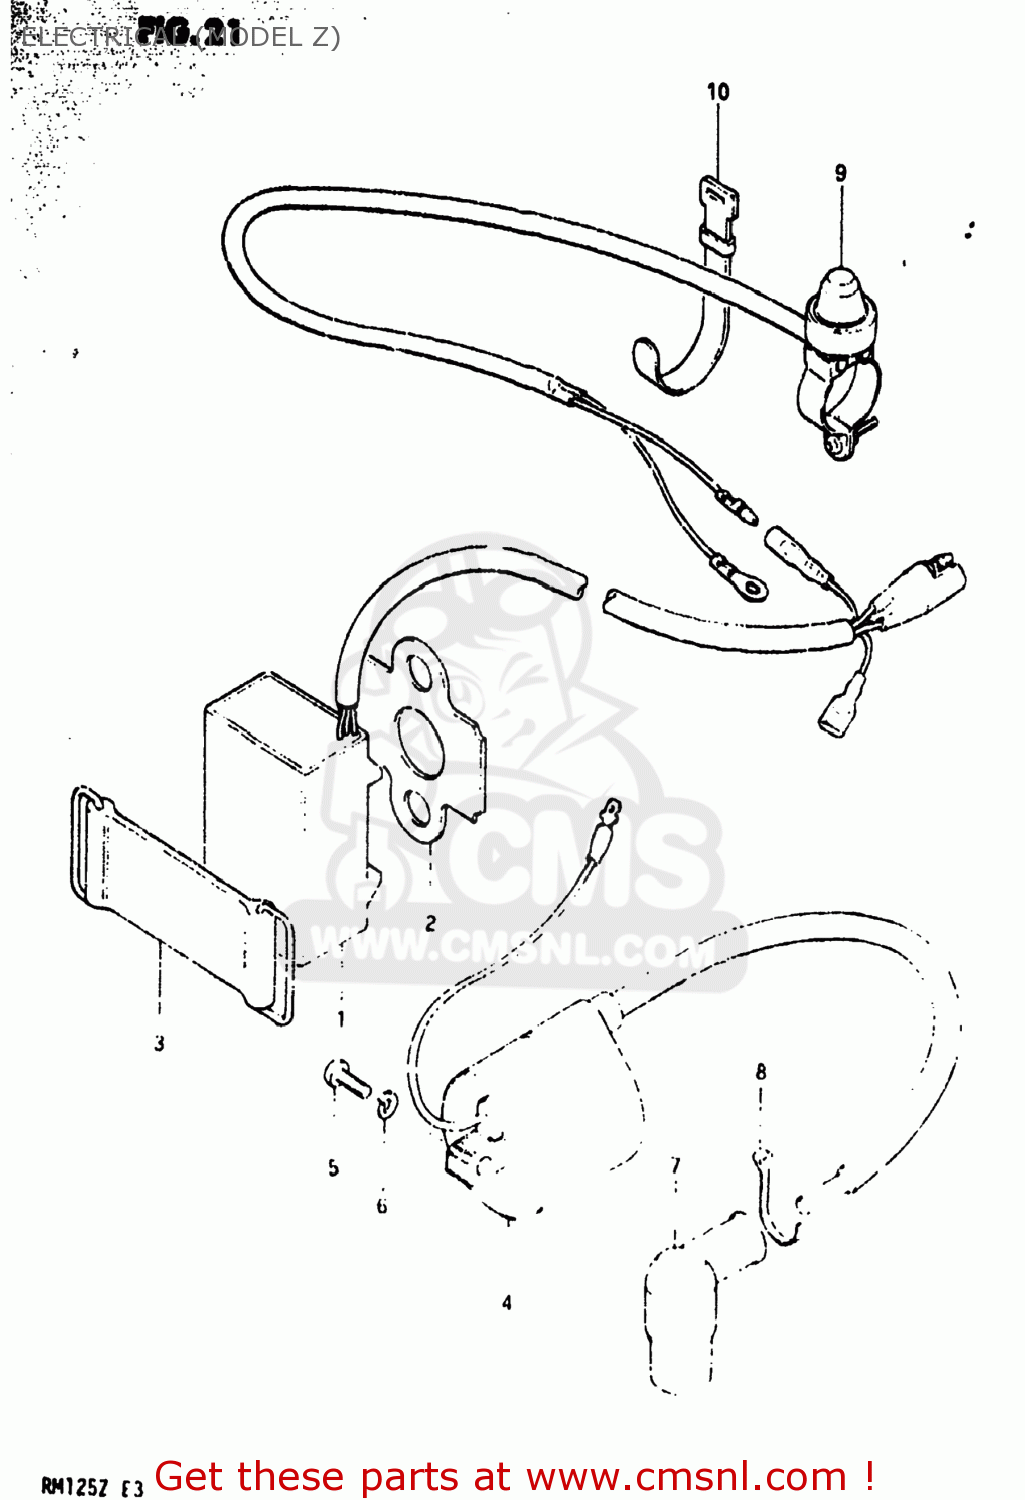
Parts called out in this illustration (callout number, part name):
1	CDI UNIT
2	PROTECTOR,CDI UNIT
3	BAND
4	COIL ASSEMBLY,IGNITION
5	SCREW
6	LOCK WASHER
7	CAP,SPARK PLUG
8	CLAMP
9	SWITCH ASSEMBLY
10	CLAMP(L:120)
